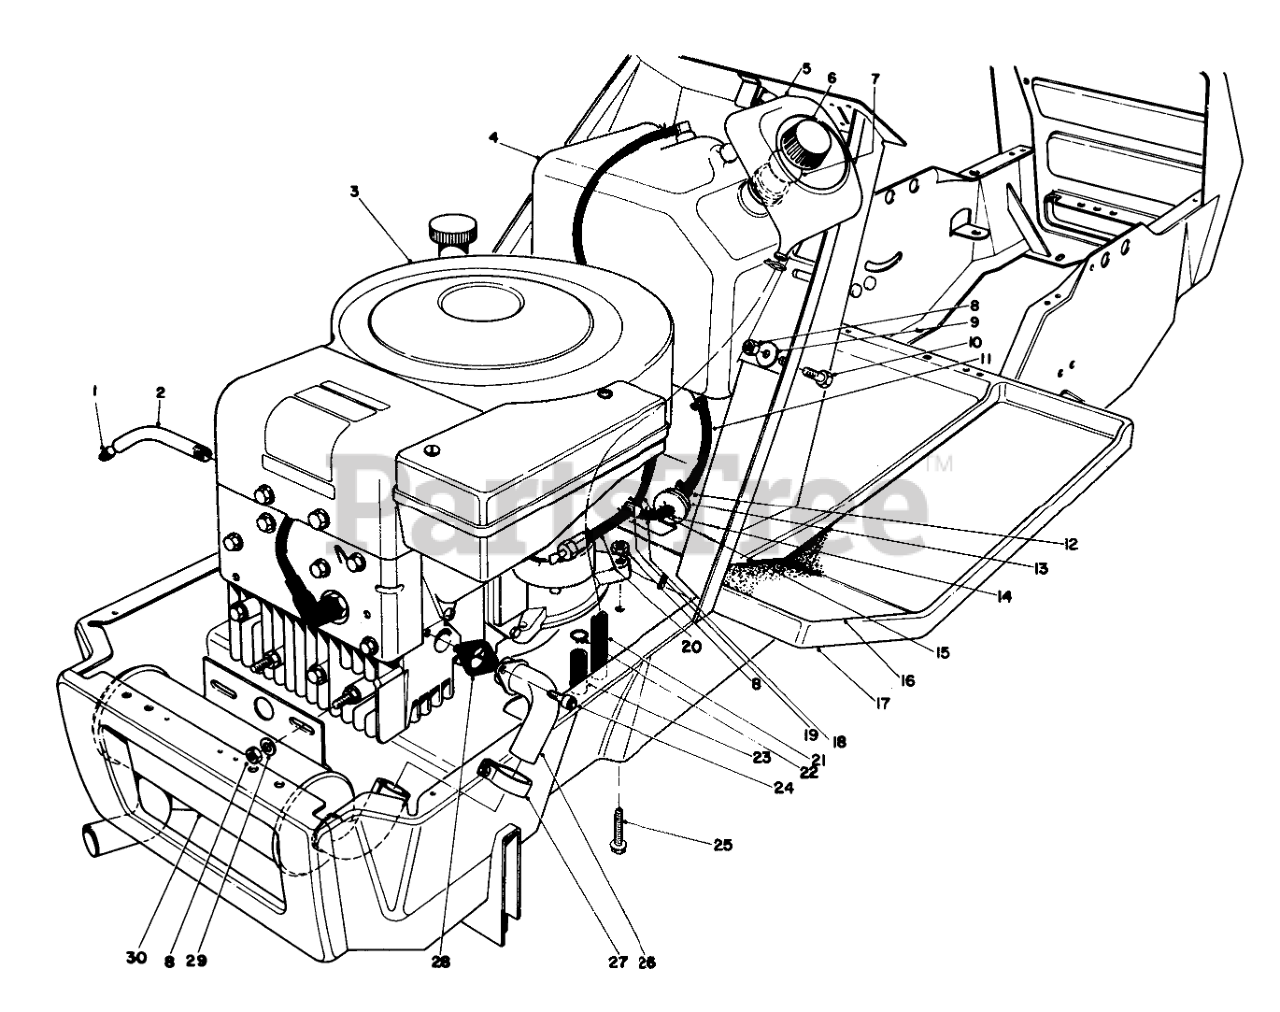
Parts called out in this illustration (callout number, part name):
1	PLUG-PIPE, SQH
2	OIL DRAIN TUBE
3	Engine
4	Gas Tank Assembly (Incl.Ref. #5)
5	Funnel Overflow
6	Gas Cap Assembly (Incl. Ref. #7)
7	Gasket Gas Cap
8	NUT-LOCK, CONE
9	WASHER
10	SCREW-HH
11	Gas Hose
12	CLAMP-HOSE
13	Nut
14	Clamp
15	Hose Gas Return
16	LH FOOT TREAD
17	Frame
18	Hose Gas
19	Fitting-Barbed Y
20	Hose Gas
21	FUNNEL HOSE
22	HOSE CLAMP
23	Hose-Carburetor Drain
24	SCREW-HSH
25	SCREW-HH
26	10 HP EXHAUST PIPE WA
27	MUFFLER CLAMP
28	Exhaust Gasket
29	WASHER-PLAIN
30	EXHAUST MUFFLER 10 HP
